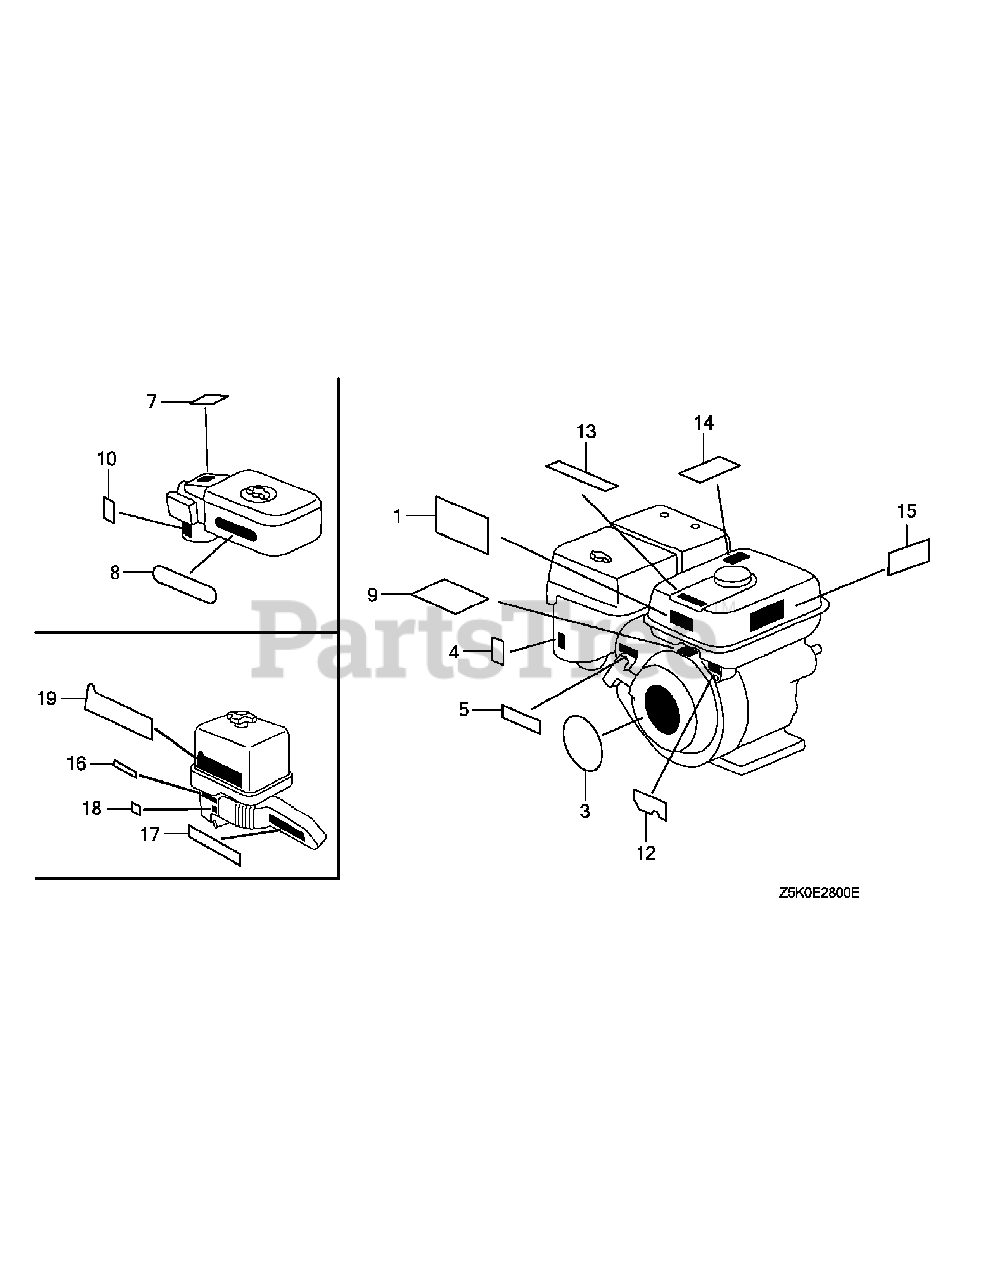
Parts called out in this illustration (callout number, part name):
1	Mark, Operator Caution(Pictograph)(Made In Thai)
3	Emblem(Gx270)
5	Mark, Throttle Indication
7	Label, Air Cleaner Caution
8	Mark, Air Cleaner Sales Point
9	Mark, Operator Caution(Pictograph)(Made In Thai)
10	Mark, Choke(Gray)
12	Mark, Engine Switch
13	Mark, Fuel Indication(English)
14	Mark, Ex. Caution(English)
15	Mark, Operator Caution(Pictograph)
16	Mark, Choke
17	Mark, Honda
18	Mark, Fuel
19	Mark, Sales Point
